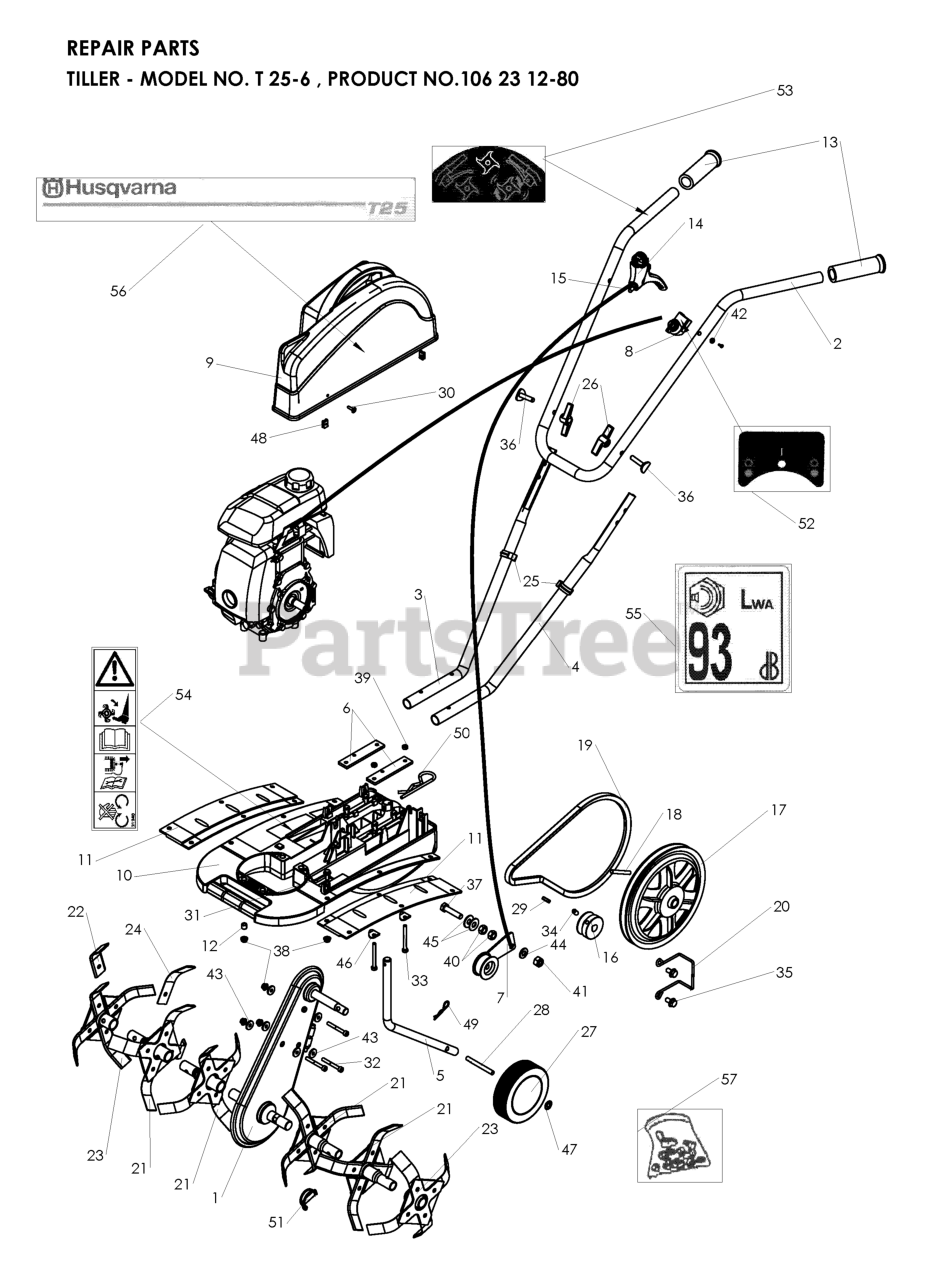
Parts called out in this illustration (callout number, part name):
15	CABLE CLUTCH
39	Blocking nut M 6 Z
44	WASHER
49	COTTER PIN
